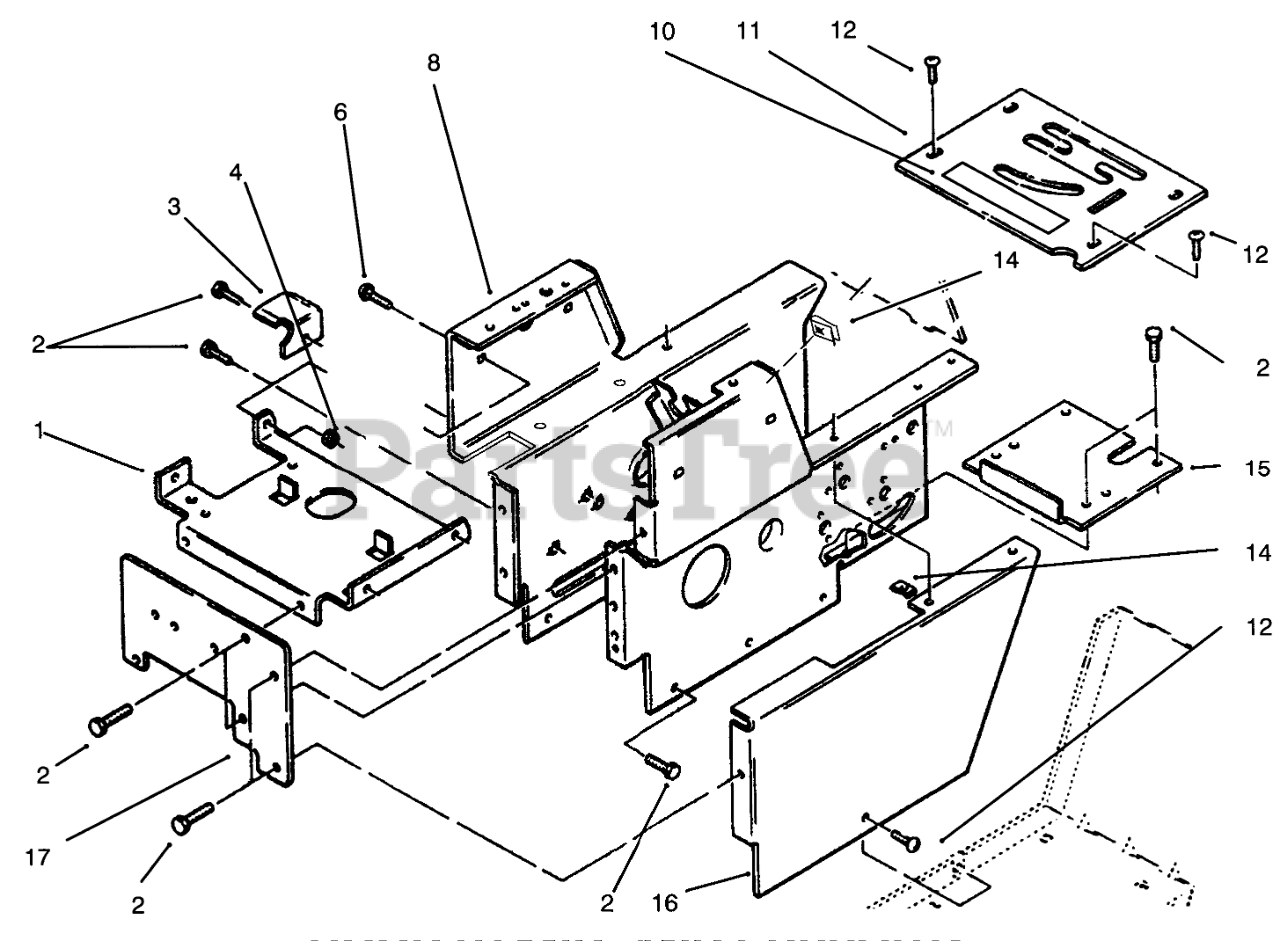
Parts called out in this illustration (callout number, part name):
1	SUPORT-BATERYB
2	SCREW
3	Bracket-Belt
4	Nut
6	BOLT CARR. 5/16X1/2 BK
8	Hoodstand
10	DECAL-DANGER
11	Plate-Shift Cover (Incl. Ref.#10)
12	Screw
15	Cover-Dust
16	Cover-Side LH
17	Front Plate
